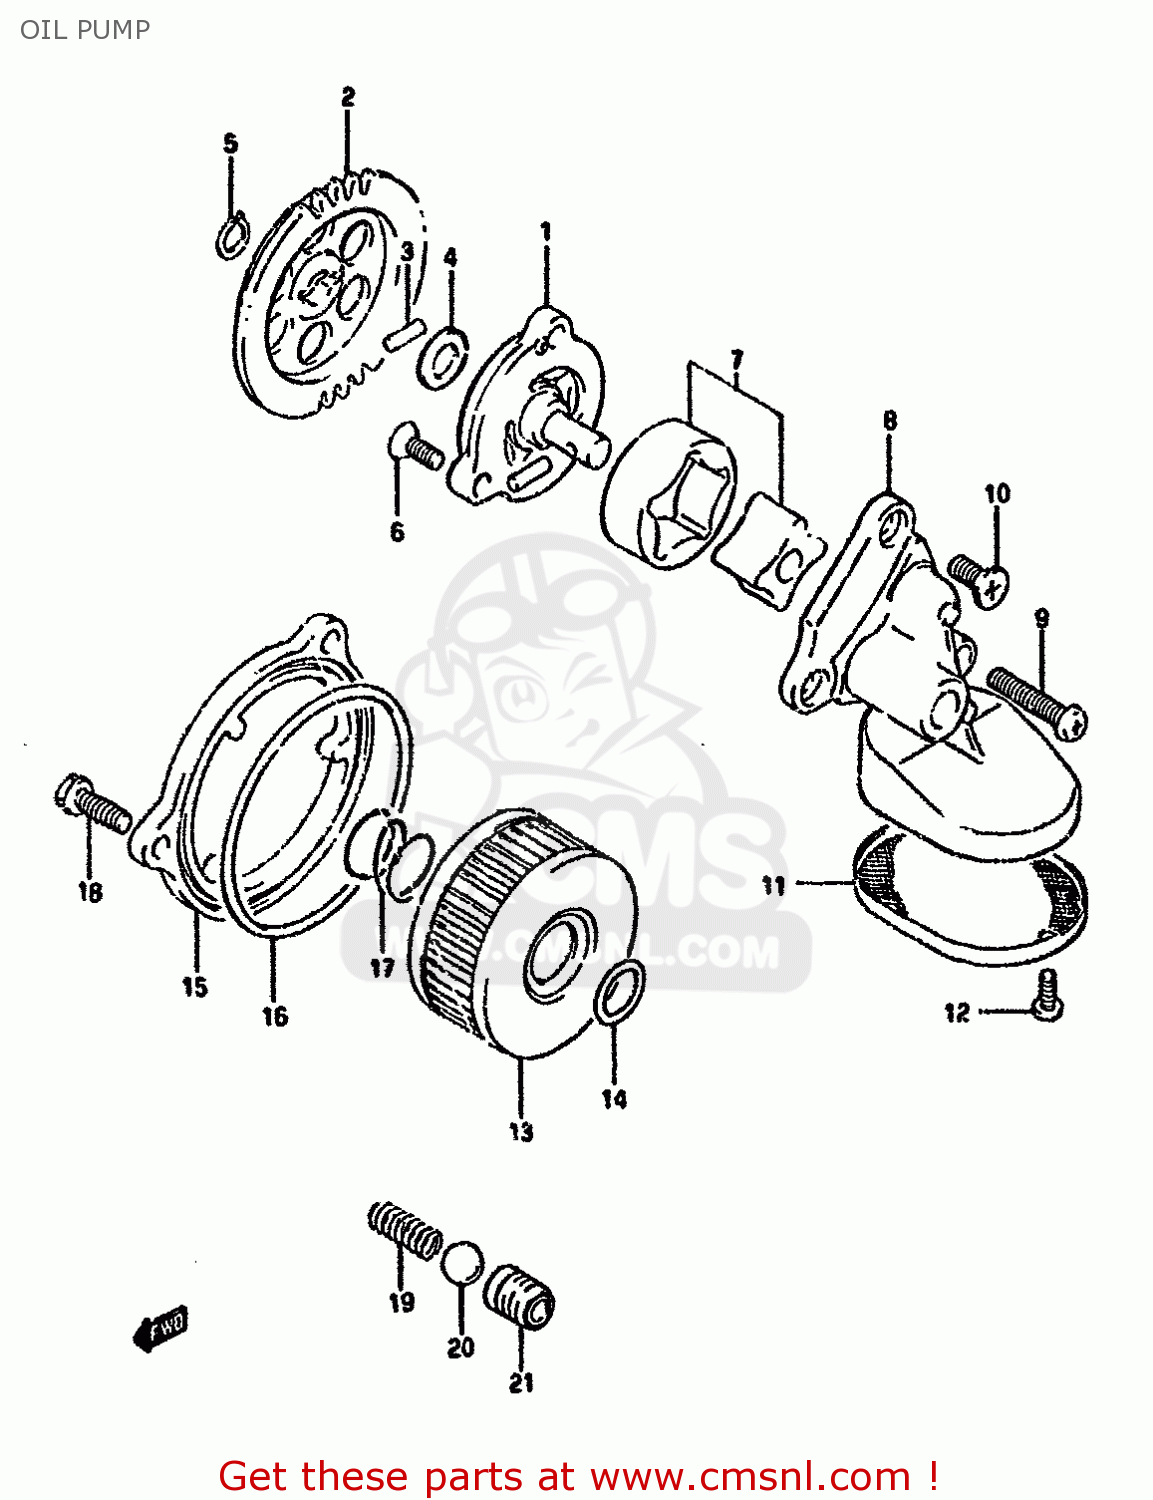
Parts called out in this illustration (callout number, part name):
1	PUMP ASSY,ENGINE OIL NO.1
2	GEAR,OIL PUMP DRIVEN (N
3	PIN(4X15.8)
4	SHIM
5	CIRCLIP,10MM
6	SCREW M6X1X16
7	ROTOR SET,OIL PUMP,NO.2
8	COVER,OIL PUMP NO.2
9	SCREW,6X30
10	SCREW M6X1X16
11	STRAINER,OIL PUMP NO.2
12	SCREW
13	FILTER ASSY,ENGINE OIL
14	O RING(D:2.4,ID:15.8)
15	CAP,OIL FILTER
16	O RING(D:2.4,ID:73)
17	SPRING
18	BOLT
19	SPRING
20	BALL
21	SEAT,OIL CHECK VALVE
